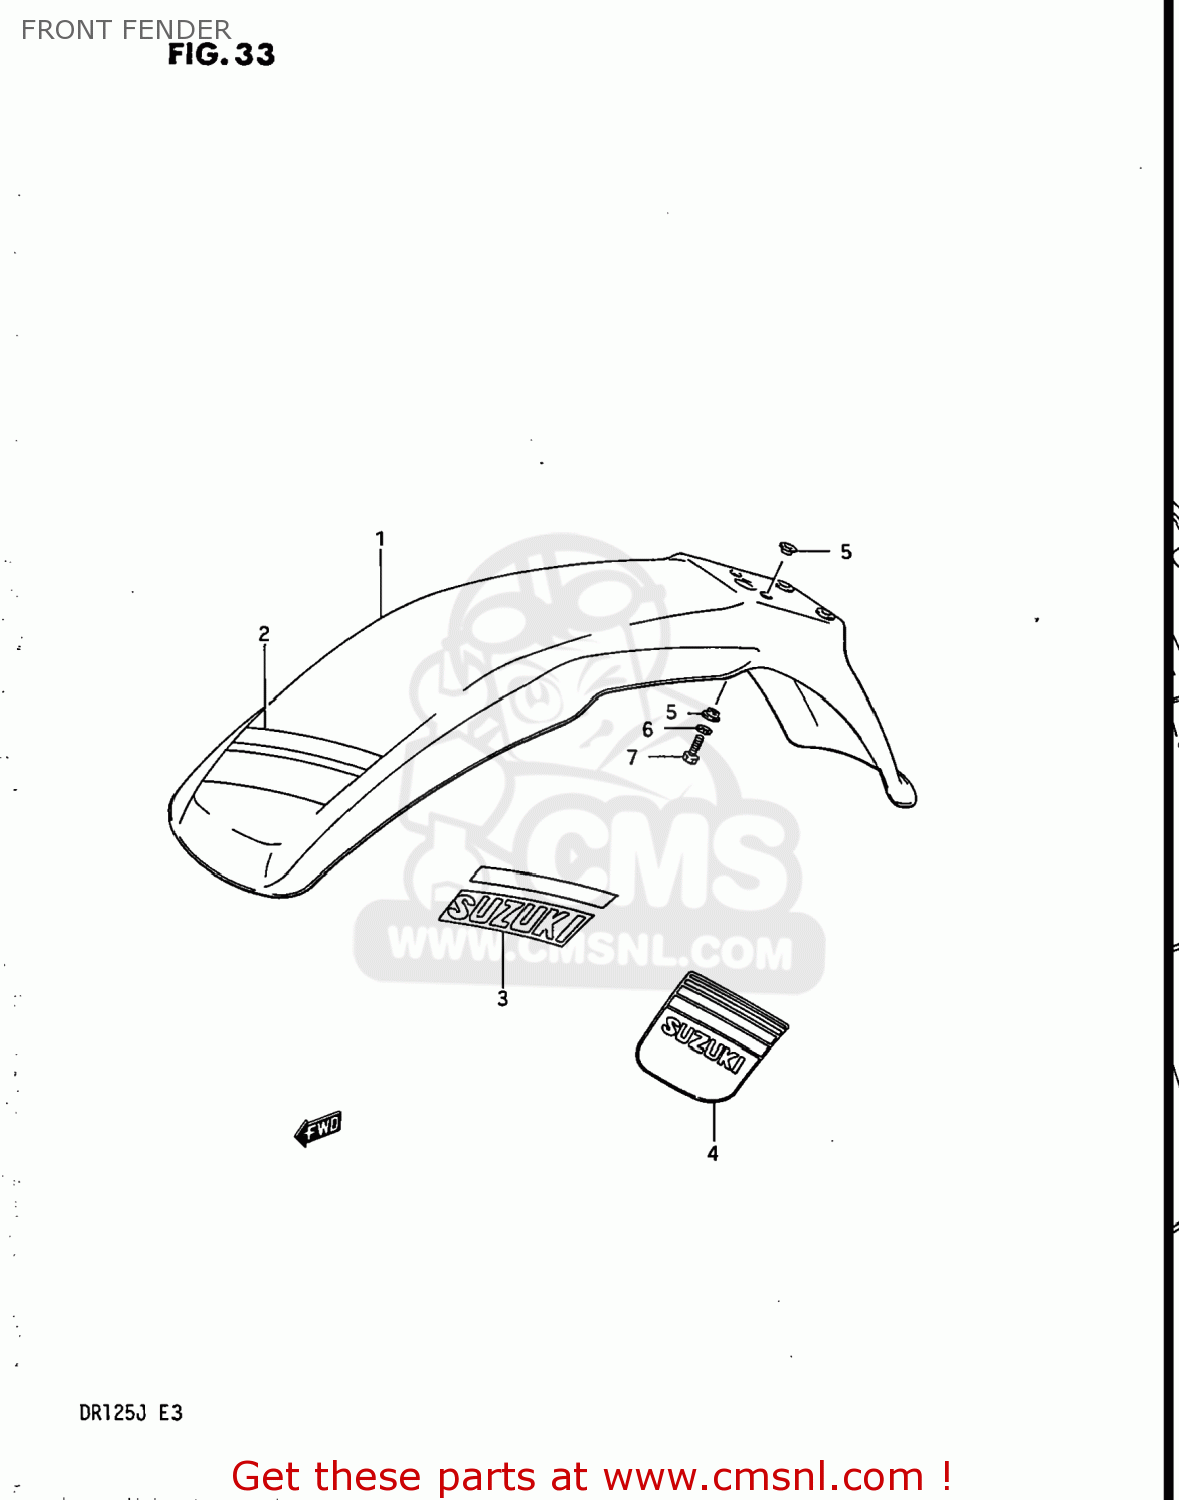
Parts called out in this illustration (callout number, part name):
1	FENDER,FRONT
2	TAPE SET,FRONT FENDER
3	TAPE,FRONT FENDER
4	TAPE,FRONT FENDER
5	WASHER
6	WASHER,LOCK
7	BOLT
